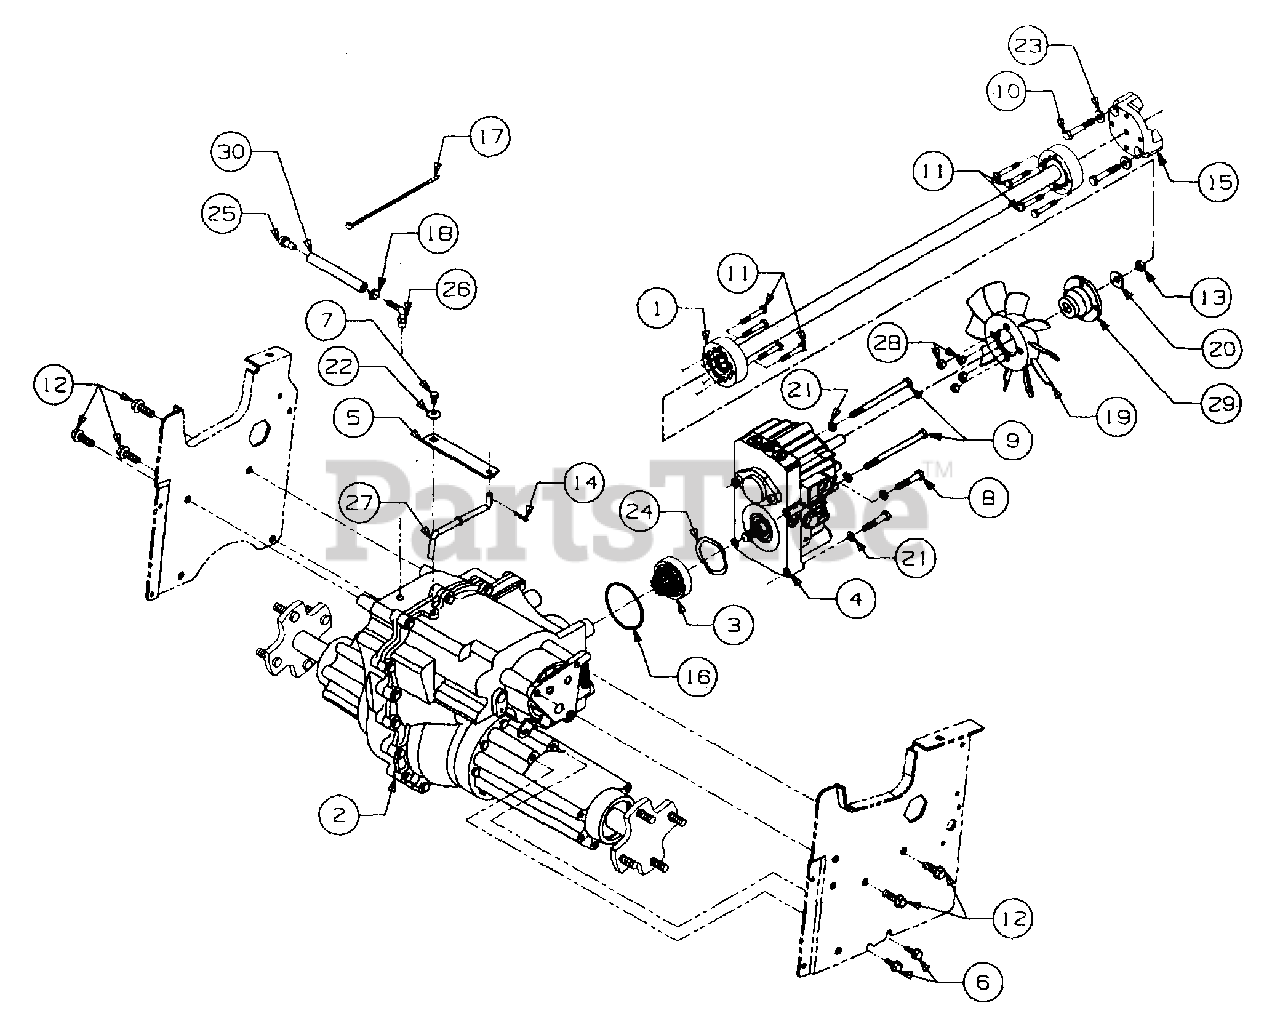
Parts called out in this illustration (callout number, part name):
1	Shaft Assembly, Drive, 27.87 Lg
2	Transmission Assembly, Hydro
3	Pinion Assembly, Input
4	Pump, Hydrostatic
5	Arm, Hydro Dump
6	Screw, Hex Wsh Tap, 5/16-18 x .75
7	Screw, Hex Wsh Hd Tap, 1/4-20 x .75
8	Screw, Hex Cap, 5/16-18 x 1.75 GR5
9	Screw, Hex Cap, 5/16-18 x 4.5 GR5
10	Screw, Hex Patch, M10-1.50 x
11	Screw, Hex Patch, 1/4-20 x 1.62 GR5
12	Screw, Hex Wsh Tap, 3/8-16 x 1.25
13	Nut, Hex Center Lock Jam, 3/8-24
14	Pin, Internal Cotter, 5/16 Dia x 1.12
15	Adapter Drive Shaft
16	O-Ring, 2.75 x .103
17	Tie, Self-Clinch Cable
18	Clamp, Hose
19	Fan, 10 Blade Cooling
20	Washer, Bell, .380 x .88 x .063
21	Washer, Lock, 5/16
22	Washer, Bell .265 x .75 x .062
23	Washer, Flat, .312 x .750 x .119
24	Wshr, Sprg, Wave, 1.96 x 2.44 x .06
26	Fitting, Elbow
27	Rod, Hydro Disengagement
28	Nut, Fan, 1/4-20
29	Adapter, Pump
30	Line, Fuel, 7in
